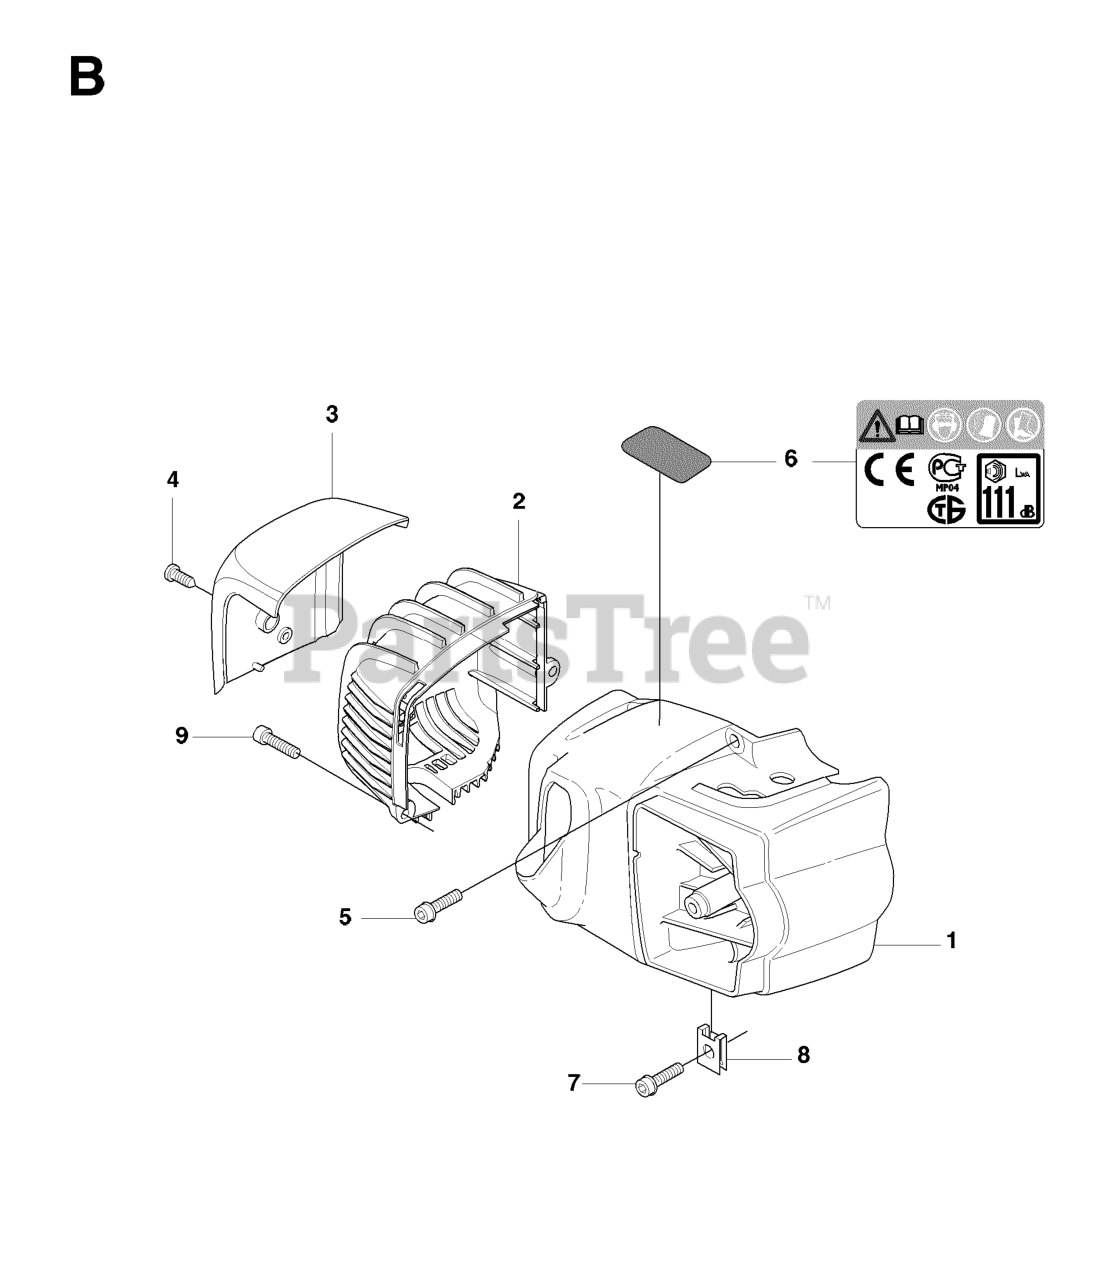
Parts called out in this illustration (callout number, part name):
2	RP MUFFLER COVER
3	MUFFLER SHIELD
6	LABEL WARNING CE
9	SCREW W/ LOCKING FLUID
